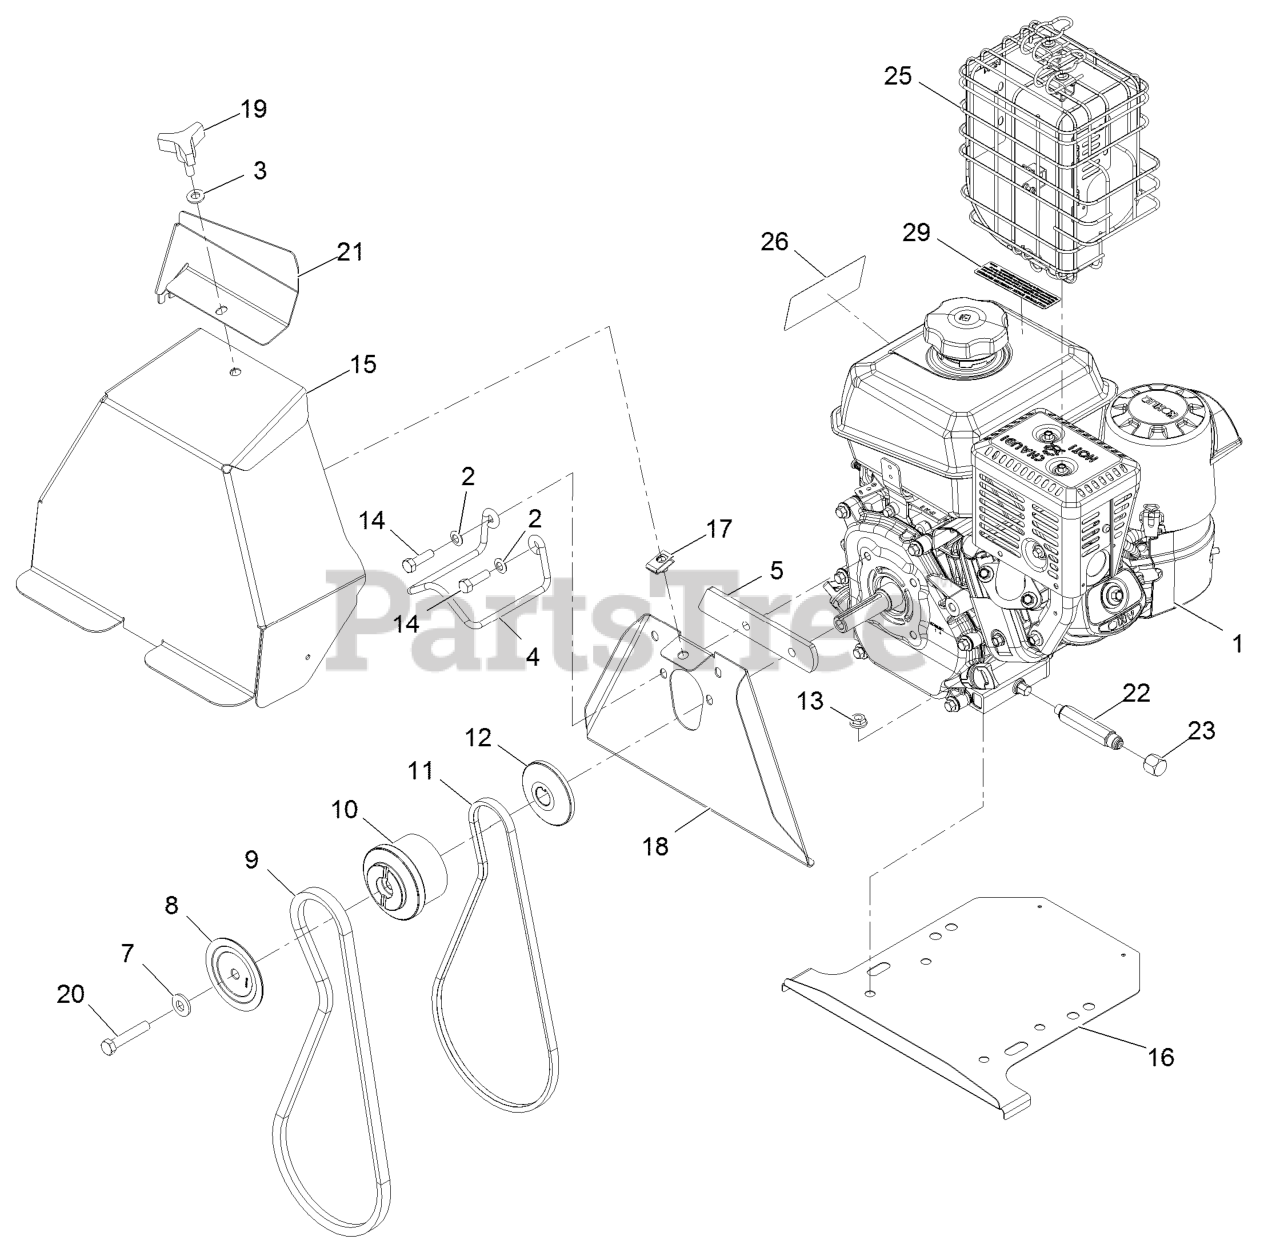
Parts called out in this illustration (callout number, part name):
2	WASHER-BELLEVILLE
3	WASHER-SPRING
5	SPACER-COVER, BELT
7	WASHER-BELLEVILLE
8	SHEAVE-HALF, IMPELLER
9	BELT-BLOWER
10	PULLEY-ENGINE, CENTER
11	V BELT-TRACTION
12	SHEAVE-HALF, TRACTION
14	SCREW-HH
15	COVER - BELT
16	SHIELD-DRIVE
18	COVER-BELT, BACK
20	SCREW-HH
21	SHIELD-ICE, KC CH270
22	ADAPTER
25	Guard-Muffler
26	Decal-Engine Fuel
29	DECAL-ARRESTER, SPARK
